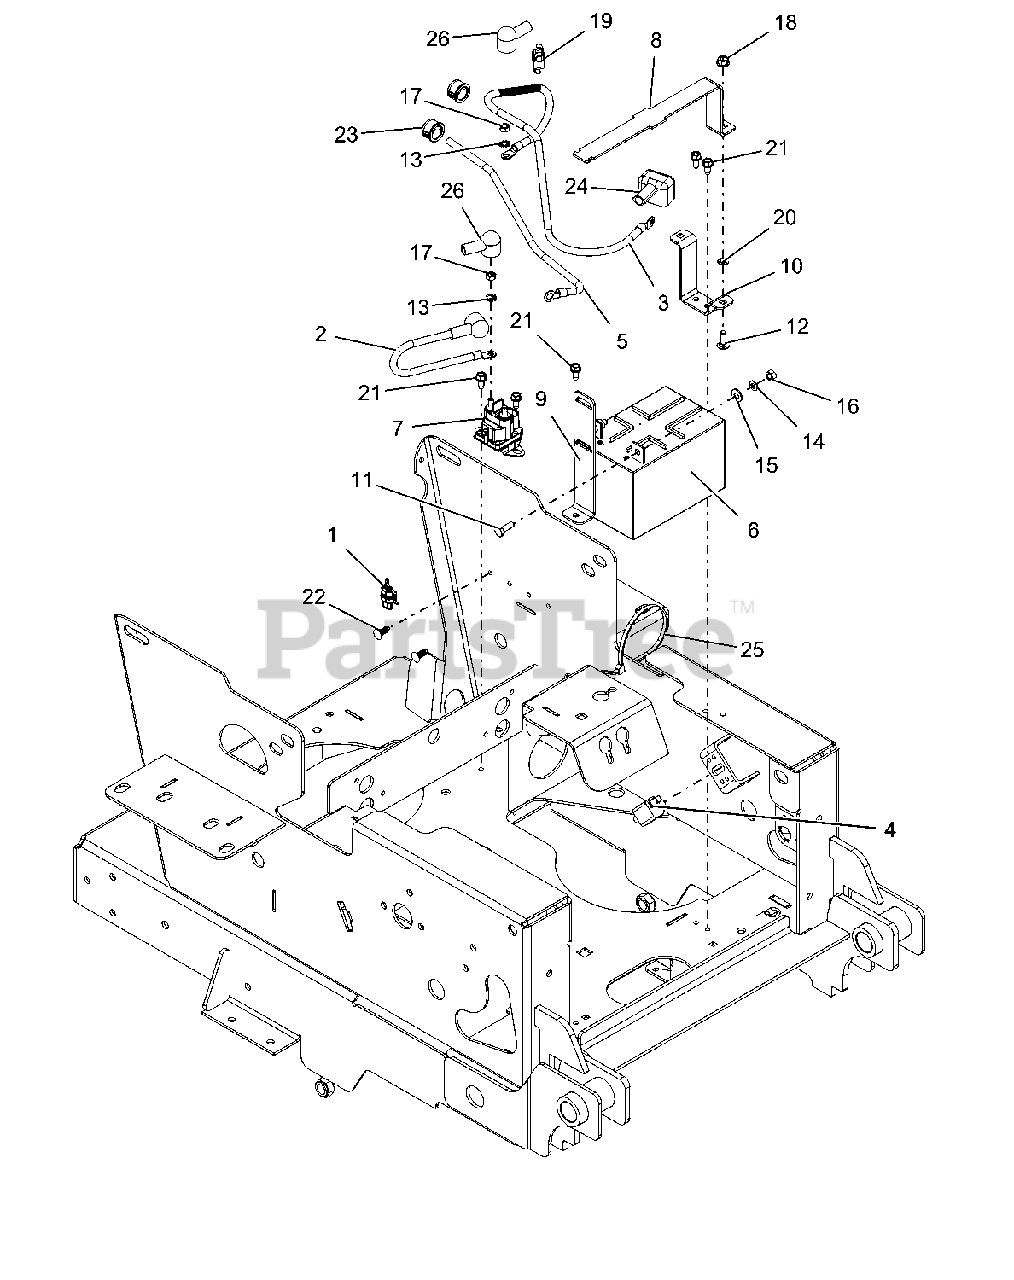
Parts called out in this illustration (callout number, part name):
1	HARNESS,WIRE(SEALED SOLENOID)
2	CABLE, POS W/(2)1/4 RING 9.0LG
3	CABLE,POS W/(2)1/4 RING 21.5LG
4	SWITCH, SINGLE POLE N.O.
5	CABLE-NEGATIVE BATTERY 24.00"
6	BATTERY, 12V 12A-190CCA
7	SOLENOID, STARTER (SEALED)
8	BRKT-BATTERY HOLD-DOWN
9	MOUNT-BATTERY HOLD-DOWN-RH
10	MOUNT-BATTERY HOLD-DOWN-LH
11	@BLT-HEX .25-20X.75 GR5 YWZC
12	@BLT-RDHDSQNK .25-20X.75 G5YZ
13	@WSHR-LK-EXT.262X.502X.026YWZC
14	@WSHR-LK .25X.062 REG YWZC
15	@WSHR-FL-STL.281X.62X.065 YWZC
16	@NUT-HEX .25-20 YWZC
17	NUT-HEX M6X1.0 YWZC
18	@NUT-LK-TOP-FLG .25-20 YWZC
19	CLIP,T,.31-.38,
20	NUT-PUSH .25X.50 O.D.
21	SCR-TAP .25-20X.50 HWH TR YWZ
22	RIVET, .25 NYLON PANEL
23	BUSH, PANEL SNAP .687X.875X.56
24	INSULATOR
25	CABLE TIE LG 5-1/2
26	BOOT, EYELET TERMINAL
